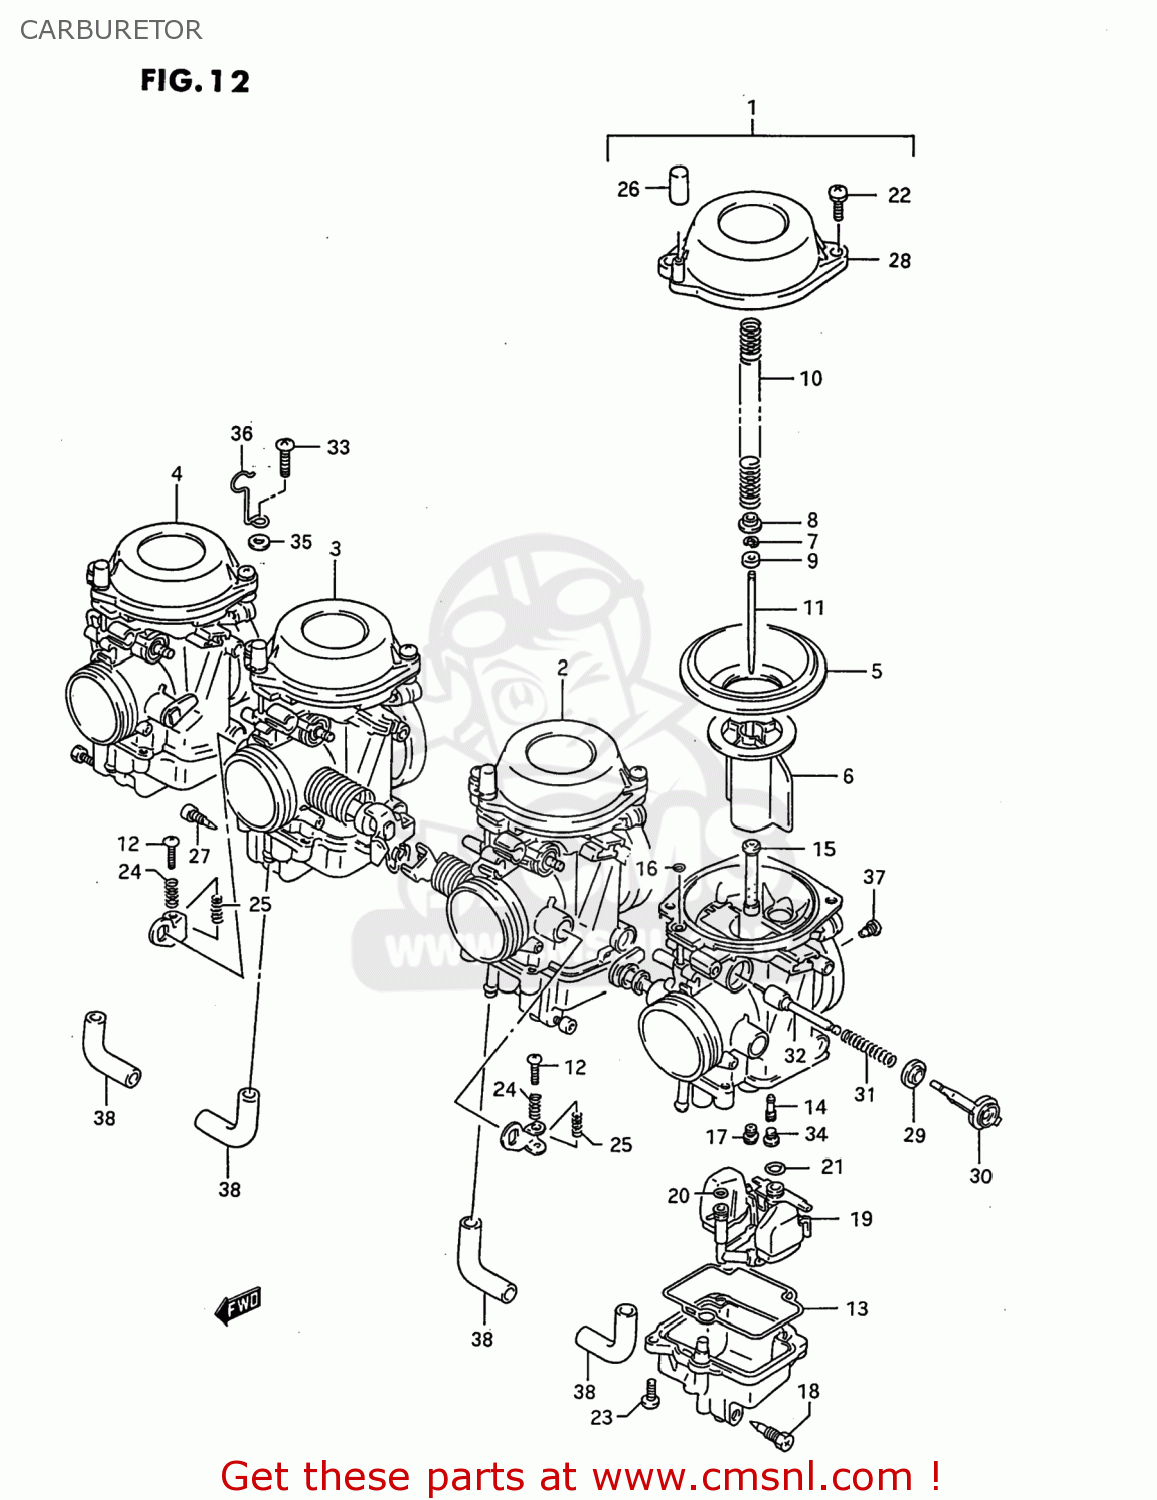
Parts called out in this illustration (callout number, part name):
1	CARBURETOR ASSY,L
2	CARBURETOR ASSEMBLY,MIDDLE,LEFT
3	CARBURETOR ASSY,MR
4	CARBURETOR ASSEMBLY,RIGHT
5	DIAPHRAGM
6	VALVE,PISTON
7	CLIP,NEEDLE
8	RING
9	RING
10	SPRING
11	NEEDLE,JET
12	SCREW
13	GASKET,FLOAT CHAMBER (NAS)
14	JET,PILOT(32.5)
15	JET,NEEDLE(Y-1M)
16	O RING
17	JET,MAIN(105)
18	PLUG,DRAIN
19	FLOAT/NEEDLE VALVE ASSEMBLY
20	O RING
21	O-RING,NEEDLE VALVE
22	SCREW
23	SCREW
24	SPRING
25	SPRING
26	CAP
27	SCREW,DRAIN
28	COVER,DIAPHRAGM
29	CAP,STARTER
30	HOLDER,GUIDE
31	SPRING
32	PLUNGER ASSEMBLY
33	SCREW
34	PLUG
35	WASHER
36	CLIP
37	JET,AIR
38	HOSE
